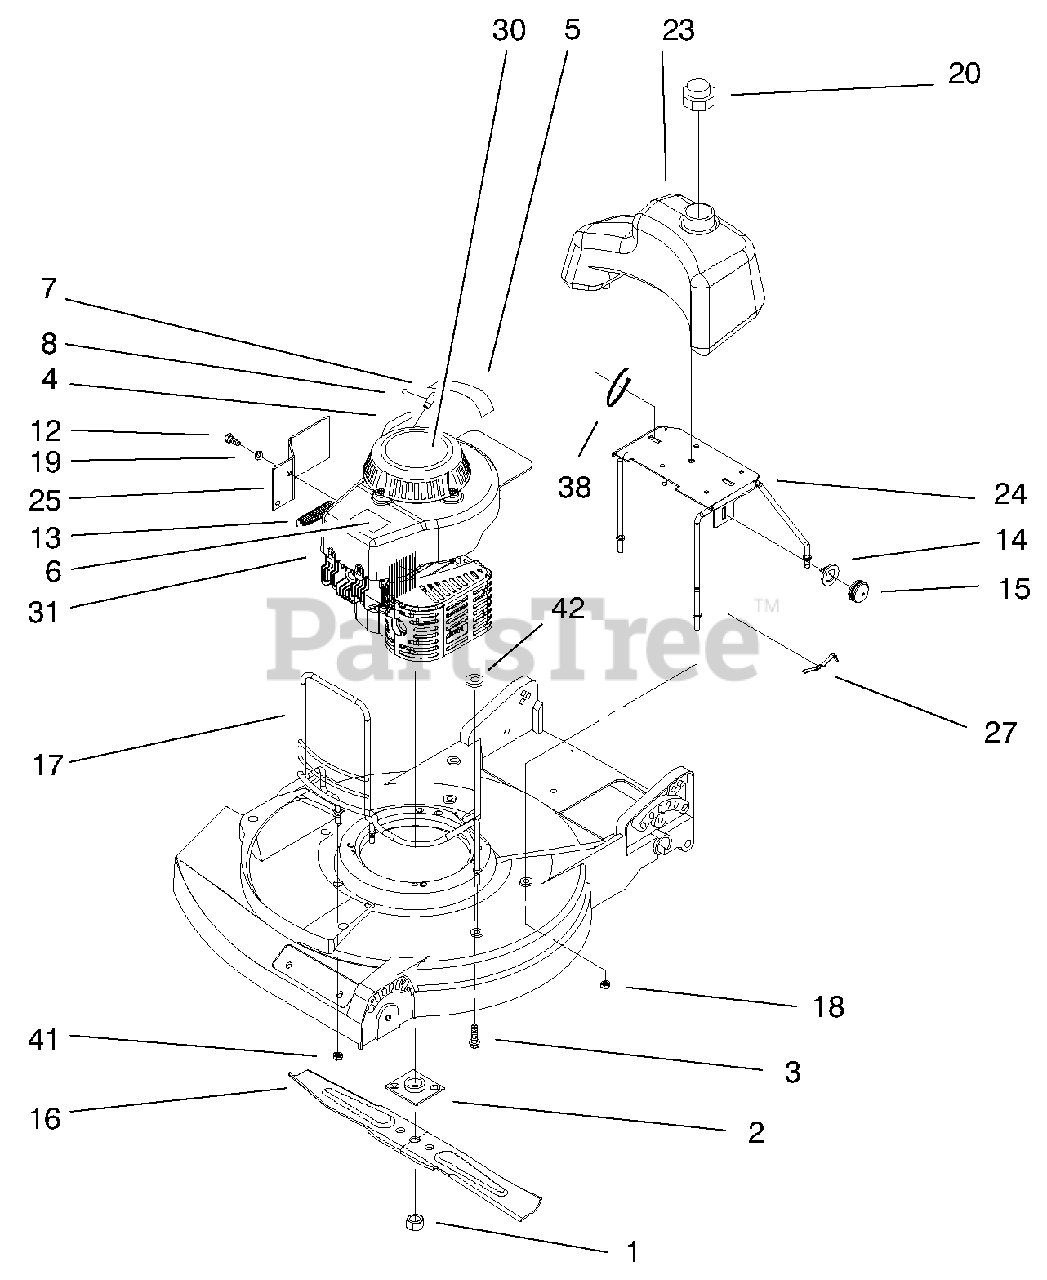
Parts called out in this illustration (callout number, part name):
1	Nut-Blade
2	ASM-Plate & Collar
3	Screw-Sems
4	Gas Line
5	Decal-Fuel Mix
6	Decal-Lawn Boy
7	Rope Stop
12	Screw-HH
13	Spring-Compression
14	Body-Primer
15	Bulb-Primer
16	Blade-21" Whirl
17	Guard-Engine
18	Locknut
19	Washer-Lock
20	ASM-Fuel/Oil Cap
21	Nut-Throttle Cable
22	Screw-Throttle Cable
23	Tank-Fuel
24	Tank Bkt ASM
25	Guard-Brake
28	Screw-Sems
29	Screw-Tf Acorn Hd
30	Decal-Recoil
31	Engine ASM
38	Tie Strap
